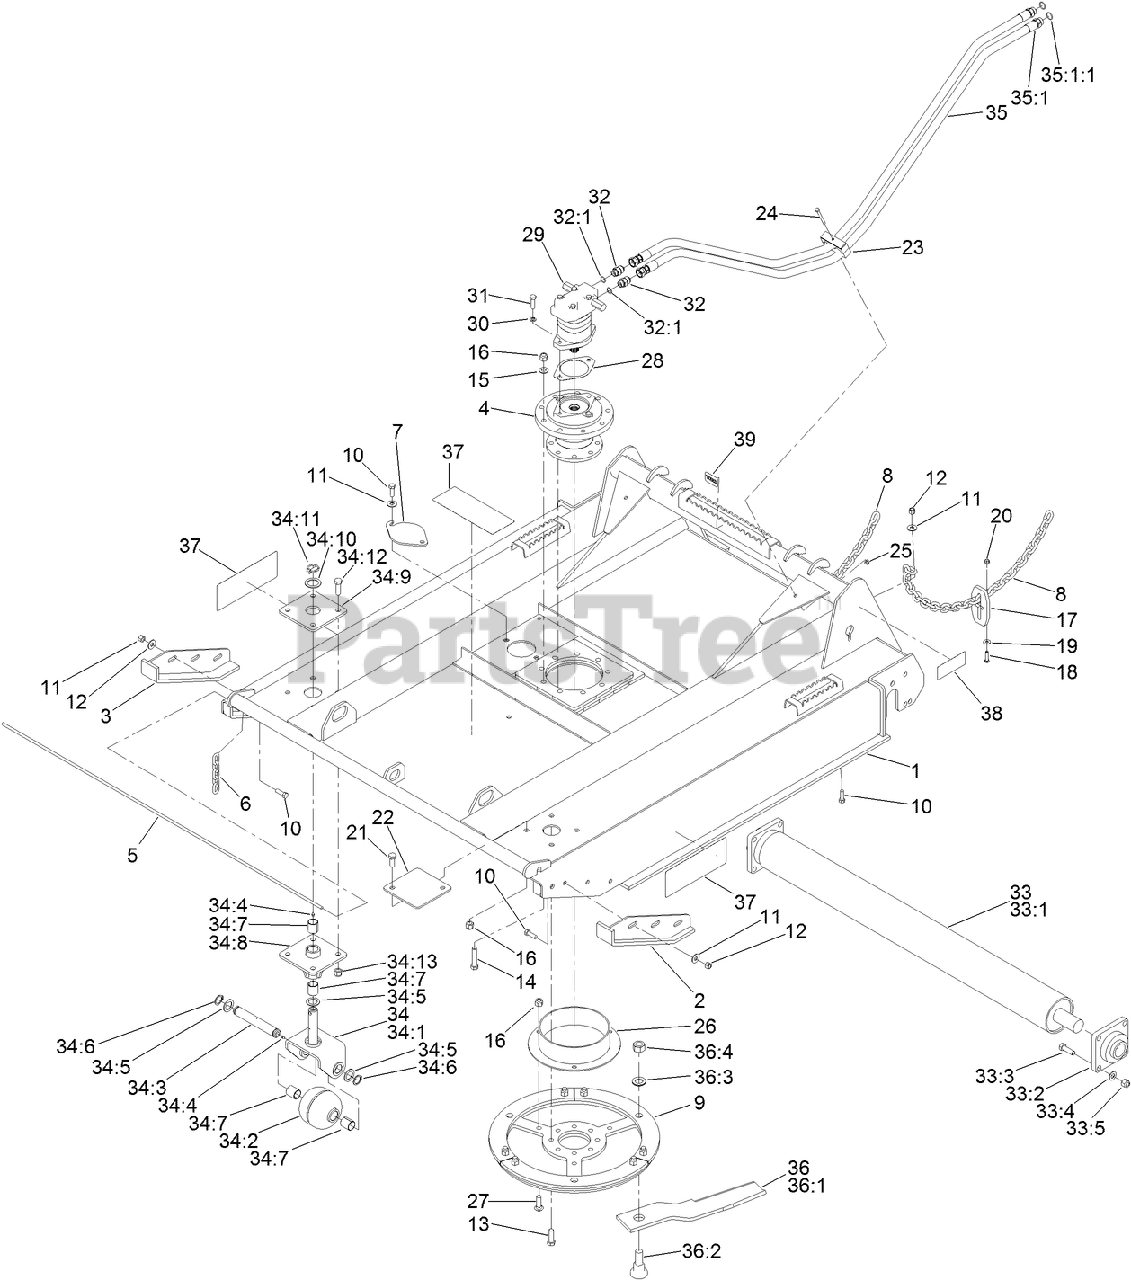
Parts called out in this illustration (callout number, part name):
1	DECK ASM
2	PLATE-SKID, LH
3	PLATE-SKID, RH
4	ADAPTER-BEARING
5	ROD-SUPPORT, CHAIN
6	CHAIN-LINK
7	COVER-ACCESS, BLADE BOLT
8	CHAIN-LIMITING, LIFT
9	BLADE CARRIER ASSEMBLY
10	SCREW-HH
11	WASHER-FLAT
12	NUT-LOCK, NI
13	SCREW-HH
14	SCREW-HH
15	WASHER-FLAT
16	NUT-LOCK, NI
17	PLATE-LIMITING, LIFT
18	SCREW-HH
19	WASHER-FLAT
20	NUT-HF, NI
21	SCREW-HH
22	PLATE-COVER, CASTER
23	CLAMP-HOSE
24	SCREW-HH
25	NUT-HF, NI
26	GUARD-SPINDLE
27	BOLT-CARR
28	GASKET
29	HYDRAULIC MOTOR ASM
30	SCREW-HH
31	SCREW-HH
32	FITTING-STRAIGHT
32:1	O-RING
33	BRUSH CUTTER ROLLER ASM
33:1	ROLLER ASM
33:2	BEARING-FLANGED
33:3	SCREW-HH
33:4	WASHER-FLAT
33:5	NUT-LOCK, NI
34	BRUSH CUTTER CASTER ASM
34:1	SWIVEL-CASTER
34:2	WHEEL-CASTER
34:3	PIN-PIVOT
34:4	FITTING-ZERK
34:5	WASHER
34:6	RING-RETAINING, EXTERNAL
34:7	BUSHING
34:8	MOUNT-LOWER, CASTER
34:9	PLATE-CASTER
34:10	WASHER
34:11	PIN-LYNCH
34:12	SCREW-HH
34:13	NUT-LOCK, NI
35	HYD HOSE ASM
35:1	FITTING-STRAIGHT
35:1:1	O-RING
36	60IN ROTARY BLADE KIT
36:1	BLADE
36:2	BOLT-BLADE
36:3	WASHER-LOCK
36:4	NUT-LOCK
37	DECAL-DANGER
38	DECAL-WARNING
39	DECAL
